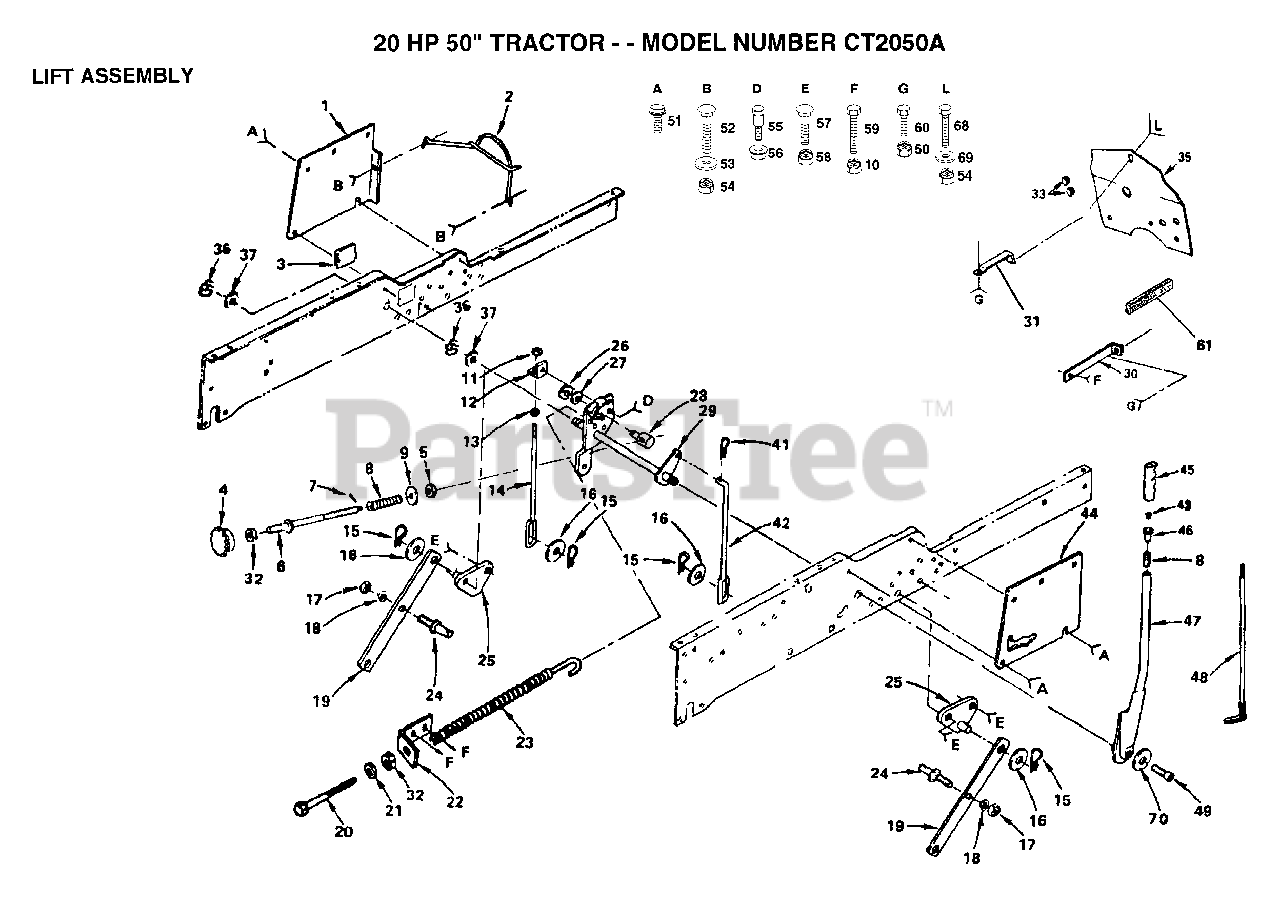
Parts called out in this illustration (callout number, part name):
2	"GUARD, BELT"
3	COVER ACCESS
4	KNOB INF 3/8-16
5	NUT T
6	ROD ADJ. T
8	SPRING T
9	WASHER
11	NUT
12	BRACKET T
15	SPRING H
17	NUT
18	LOCKWASHER
19	SUSPENSION ARM GT
20	BOLT-ADJ SPRING T
21	WASHER
24	PIVOT STUD GT
25	SUSP BRACKET T
26	KLIP RING
27	WASHER
28	TRUNION LT
29	SHAFT ASS'Y LIFT
32	NUT
36	E-RING
37	WASHER
42	LIFT LINK RH T
45	GRIP
48	LEVER ROD LT
49	"BOLT,HEX"
51	SCREW LT
52	BOLT
53	WASHER
55	SHOULDER BOLT T
56	NUT T
57	BOLT
58	NUT, CENTERLOCK
59	BOLT
60	BOLT
61	FOAM STRIP T
68	BOLT
69	WASHER M
70	LOCKWASHER
